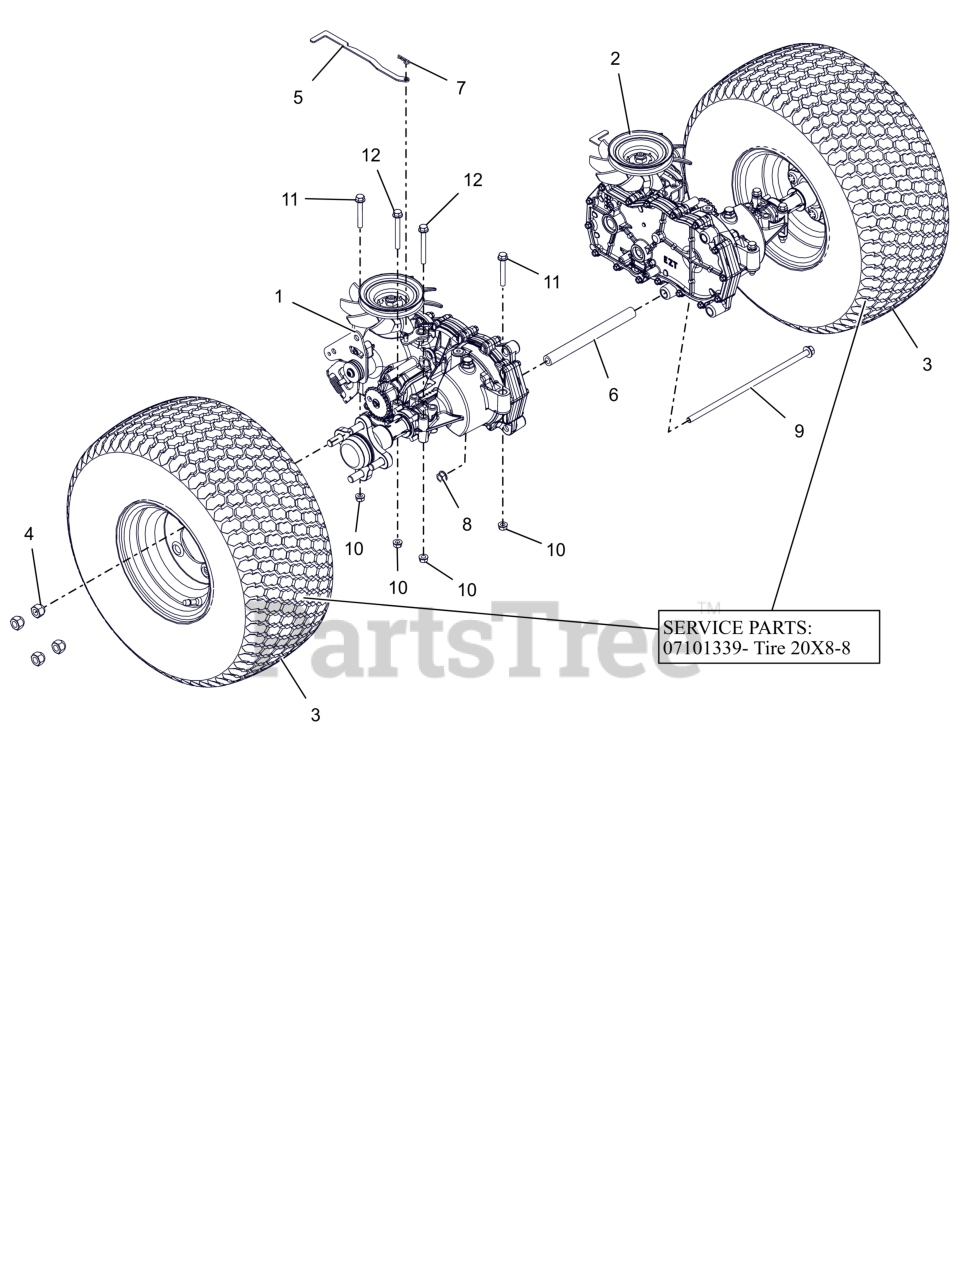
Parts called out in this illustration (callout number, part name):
1	TRANSAXLE, RH
2	TRANSAXLE, LH
3	ASSM TIRE\WHEEL, 20 X 8 -8
3	TIRE, 20X8-8
4	NUT, WHEEL .50-20 ZCC
5	BRKT, DUMP VALVE
6	SPCR, TRANSAXLE .438 ID X .750 OD X 8.18 (BLACK)
7	PIN, HAIR #213 .08X1.19 ZCC
8	NUT-LK-CTR-FLG .375-16 GF ZCC
9	BLT, HEX-FLG 0.375-16X11.5 GR5 ZC120
10	NUT,LK-CTR-FLG .31-18 GF ZCC
11	BLT,HEX-FLG .31-18X2.25 G5 ZCC
12	BLT,HEX-FLG .31-18X2.75 G5 ZCC
